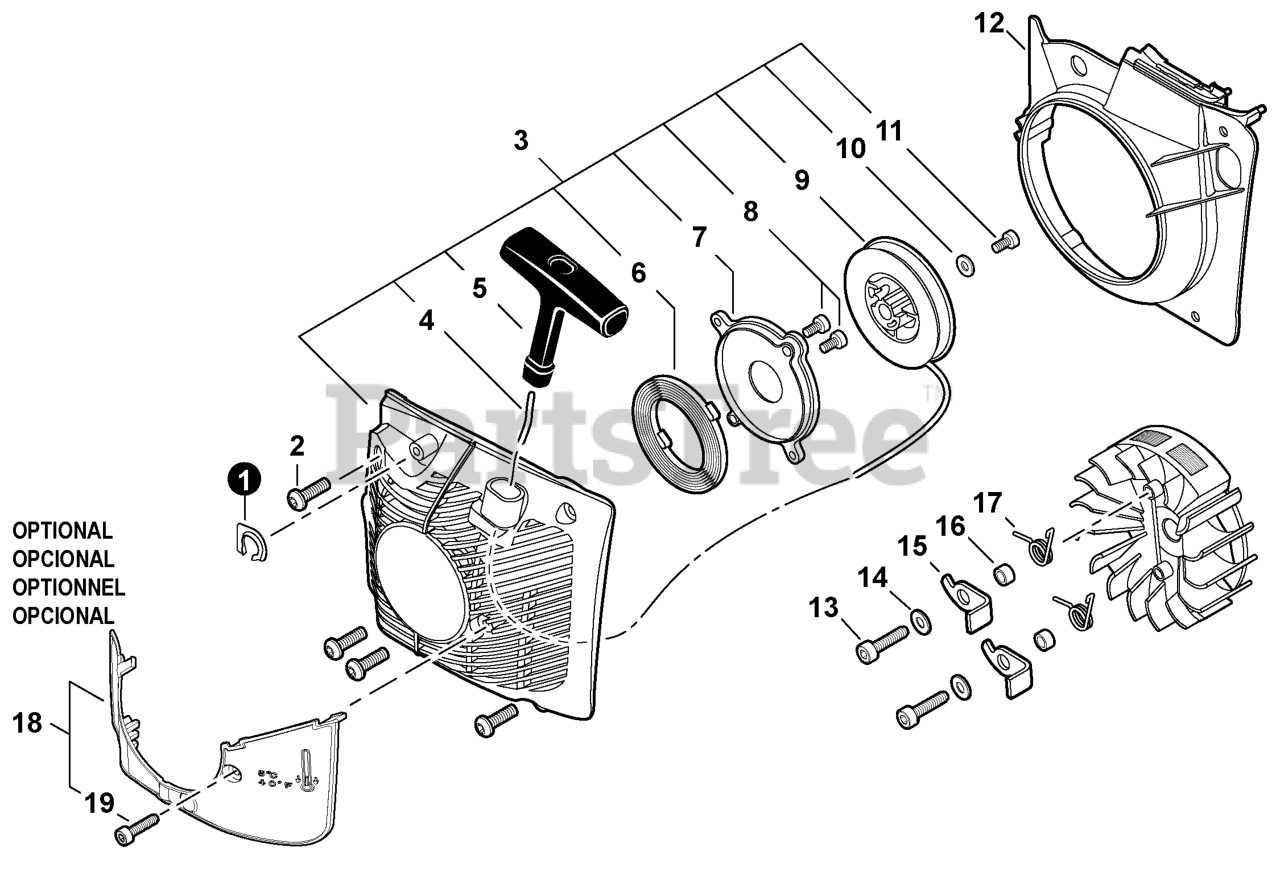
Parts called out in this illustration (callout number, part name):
1	PLATE, EYE
2	BOLT, TORX 5x20
3	STARTER ASSY, RECOIL
4	ROPE, STARTER 4x950
5	GRIP, STARTER
6	SPRING, RECOIL
7	PLATE, STARTER
8	BOLT, TORX 4x12
9	REEL, ROPE
10	WASHER 5.2x16x1.0
11	BOLT, TORX 5x10
12	COVER, FAN
13	BOLT, TORX 5x16
14	WASHER 5.5x12x0.8
15	PAWL, STARTER
16	SPACER 5.2x8x2.1
17	SPRING, TORSION
18	SHIELD KIT - SNOW
19	BOLT, TORX 4x12
